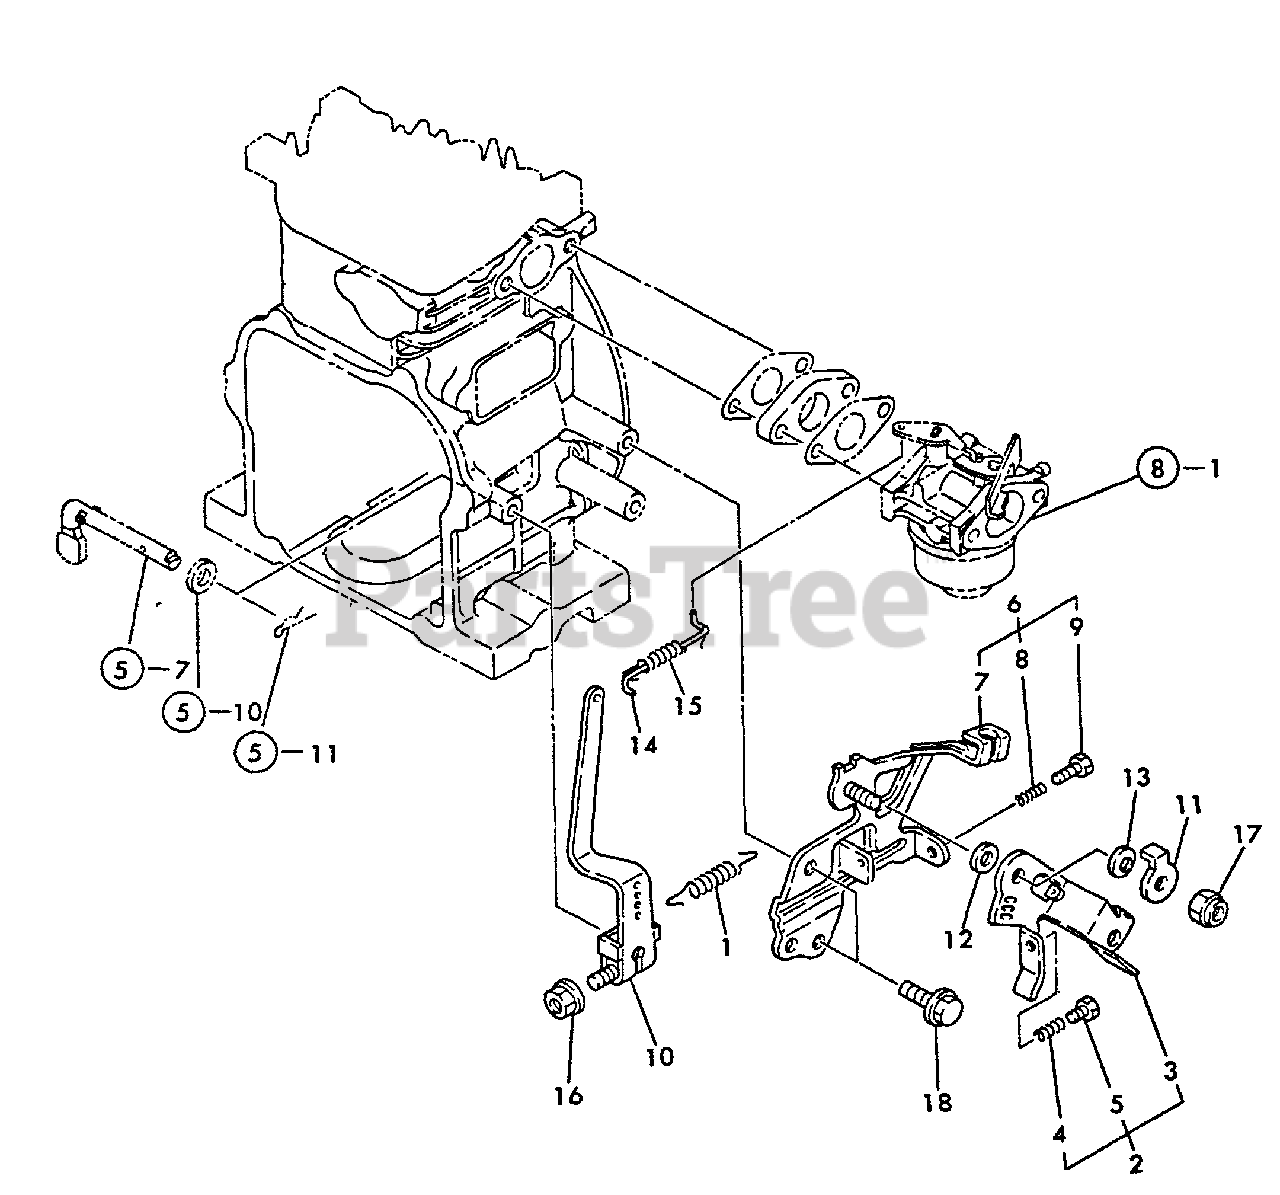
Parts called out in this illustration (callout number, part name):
1	SPRING, REGULATOR
2	HANDLE ASSY, REGULATOR
3	HANDLE, REGULATOR
4	SPRING, IDLE
5	BOLT - 4×20
6	BASE ASSY, REGULATOR
7	BASE, REGULATOR
8	SPRING, IDLE
9	BOLT - 4×25
10	LEVER, COVER
11	WASHER
12	WASHER - NYLON
13	SPRING, PLATE
14	LINK, THROTTLE
15	SPRING, THROTTLE
16	U-NUT M6
17	U-NUT
18	BOLT - 6×8 -- PLATED
